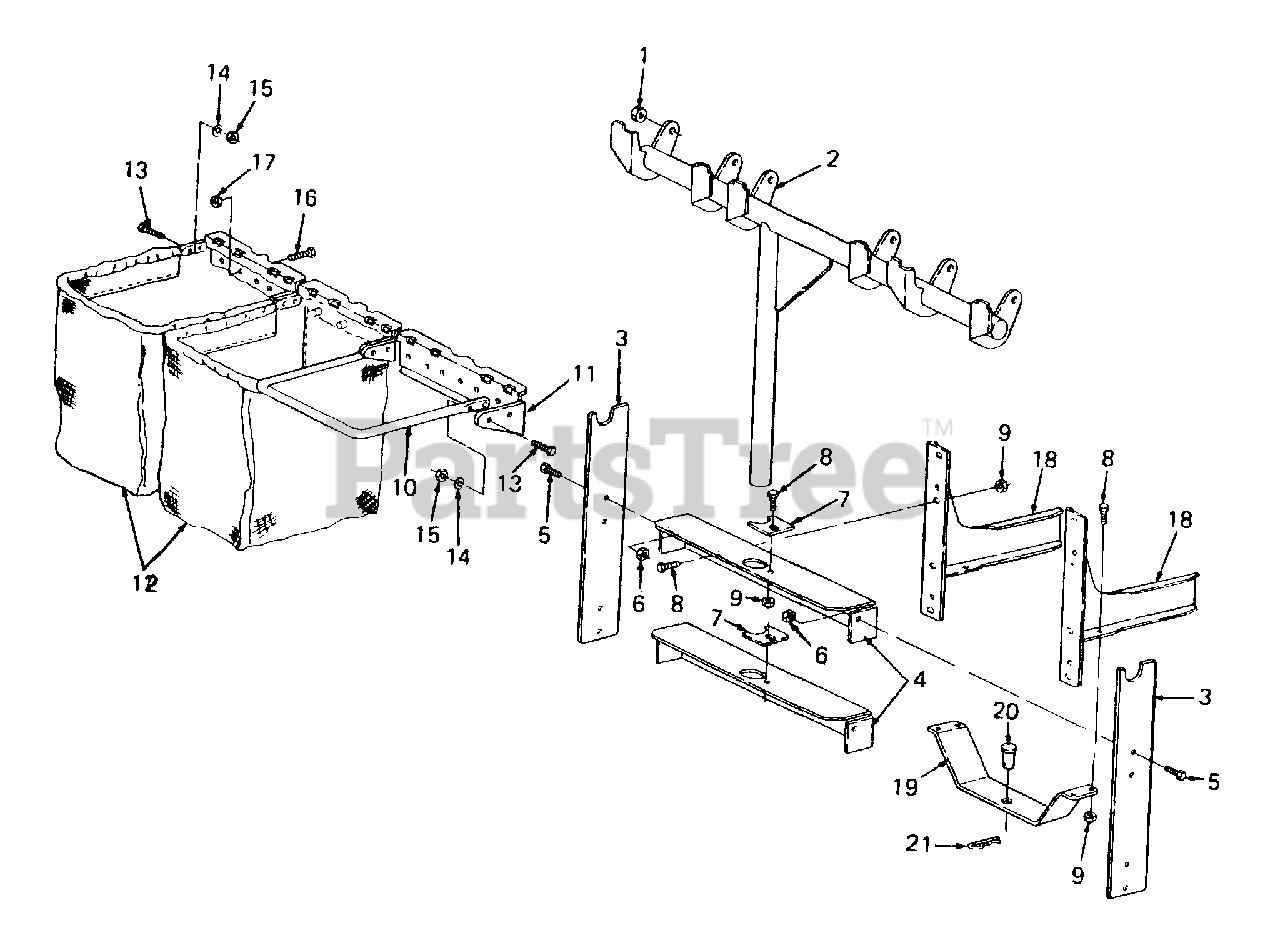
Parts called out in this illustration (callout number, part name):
1	Nut, Hex Flanged Lock, 3/8-16
2	Tube Assy., Support
3	Bracket, Support
4	Bracket, Support Tube Mounting
5	Screw, Hex Cap, 5/16-18 X .75 Lg.
6	L-Nut, Flange Top Hex, 5/16-18
7	Bracket, Support Tubing Adapter
8	Screw, Hex, 1/4-20 X .62 Lg.
9	Nut, Hex Flange Top Locknut 1/4
10	Frame, Catcher Bag
11	Bracket, Bag Frame Hanger
12	Bag, Grass Catcher
13	Screw, Hex Cap, 1/4-28 X .75 Lg.
14	Washer, Lock, 1/4
15	Nut, Hex, 1/4-28
16	Screw, Truss Mach, #10-24 X .38 Lg.
17	Nut, Hex Sems, #10-24
18	Bracket, Frame Support
20	Pin, Clevis, .62 Dia.
21	Pin, Internal Cotter
